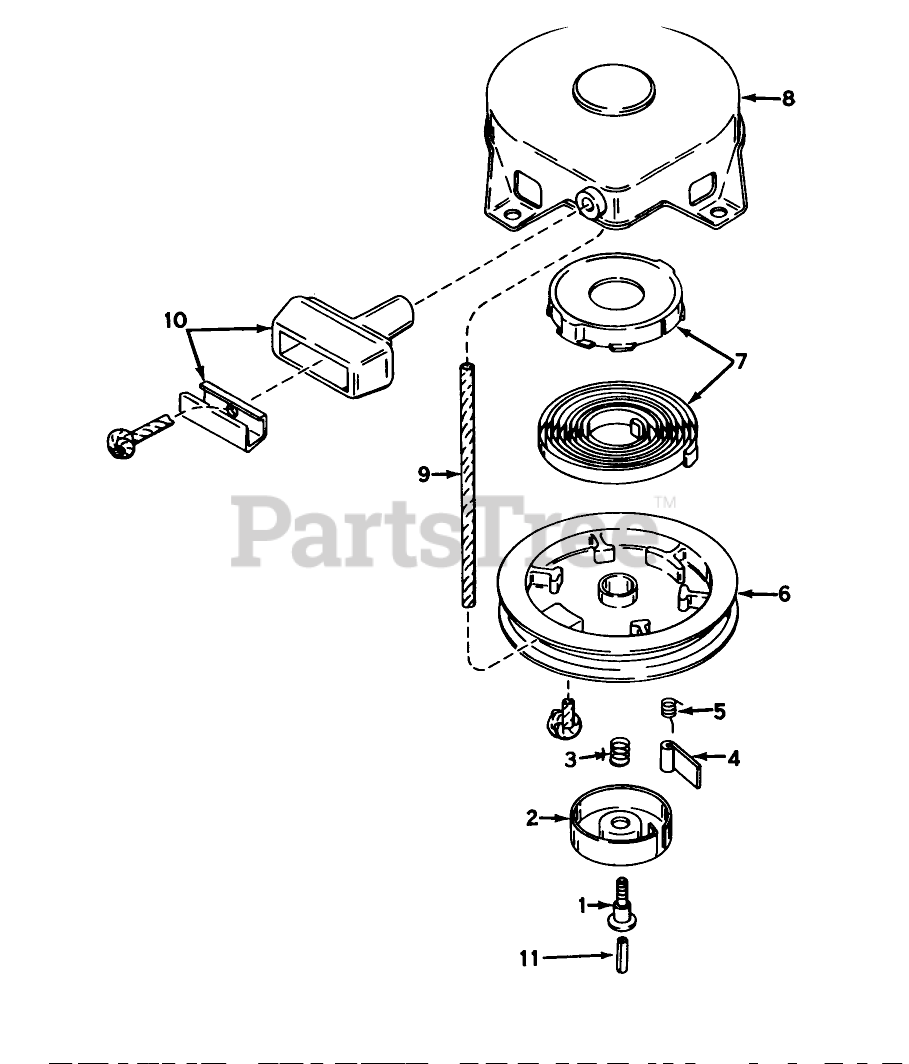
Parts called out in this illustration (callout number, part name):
1	Screw
2	Retainer
3	Spring-Brake
4	Dog-Starter
5	Spring-Dog
6	Pulley
7	Spring Keeper Assy
8	STARTER HOUSING ASSY
9	Rope Starter
10	Assy., Starter
11	Centering
